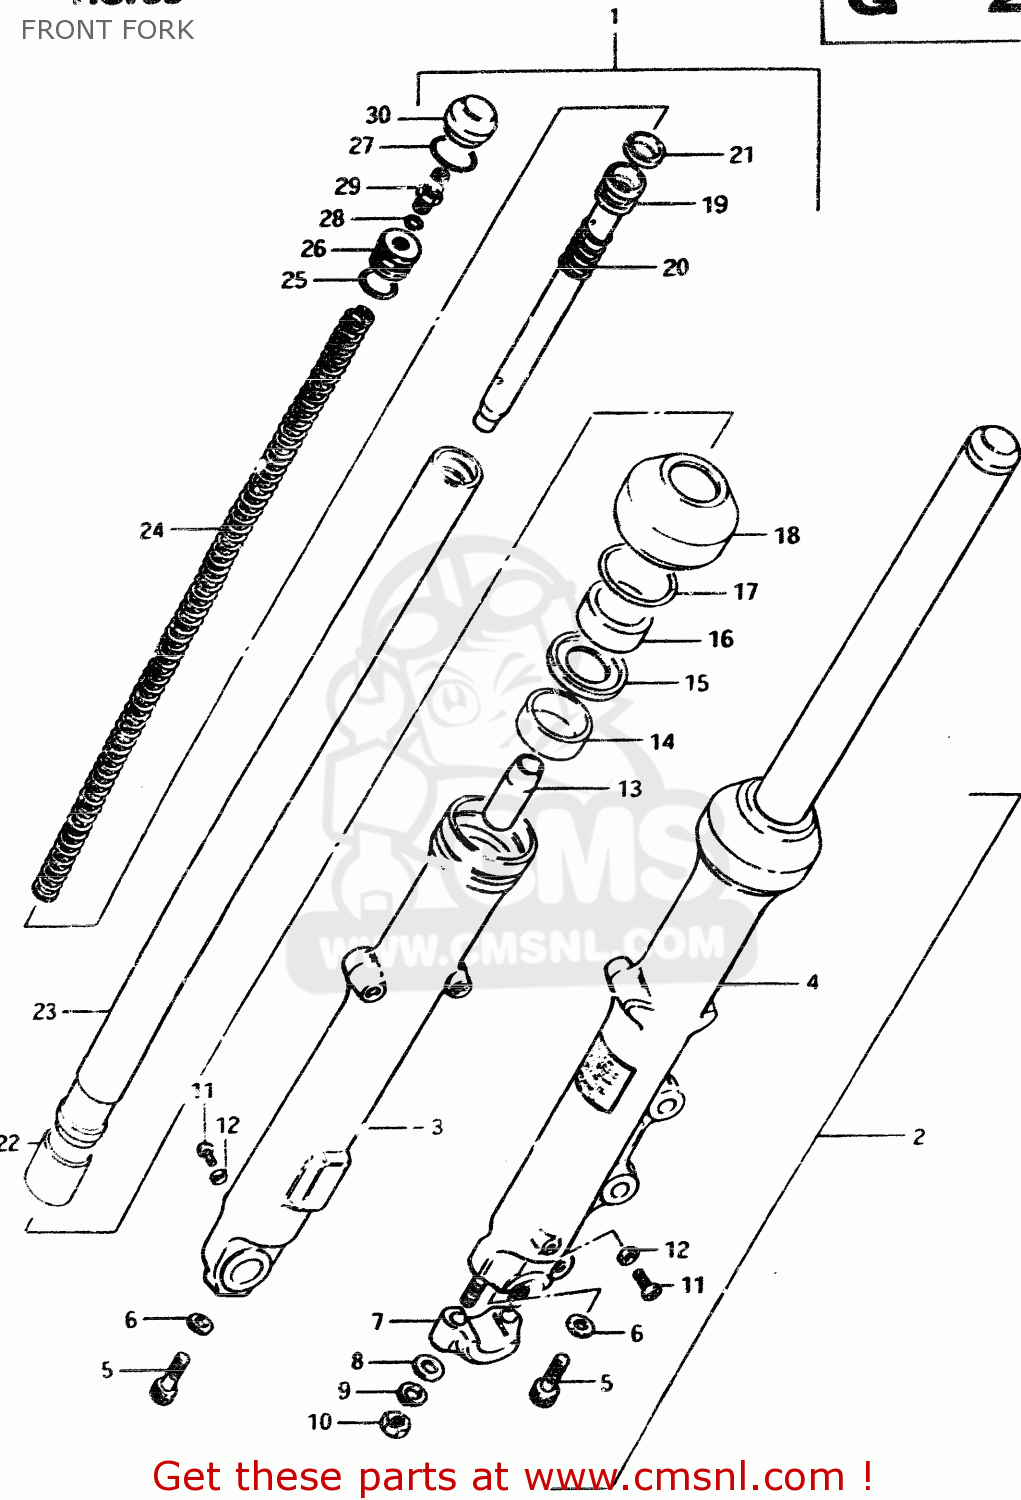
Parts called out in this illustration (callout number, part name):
1	DAMPER ASSEMBLY,FRONT FORK,RIGHT
2	DAMPER ASSEMBLY,FRONT FORK,LEFT
3	TUBE,FORK,OUTER,RIGHT
4	TUBE,FORK,LEFT,OUTER
5	BOLT(8X27)
6	GASKET (NAS)
7	HOLDER,AXLE
8	WASHER
9	LOCK WASHER
10	NUT (8MM)
11	BOLT
12	GASKET,DRAIN,PLUG (NAS)
13	PIECE,OIL LOCK
14	BUSH,GUIDE
15	SPACER,SEAL
16	OIL SEAL,FRONT FORK
17	CIRCLIP,FORK OIL SEAL
18	BOOT
19	CYLINDER,FRONT FORK
20	SPRING,FORK REBOUND
21	RING,PISTON
22	PISTON
23	TUBE,FRONT FORK,INNER
24	SPRING,FRONT FORK
25	O-RING
26	SEAT,SPRING
27	RING,STOPPER
28	O-RING
29	VALVE,AIR
30	CAP
